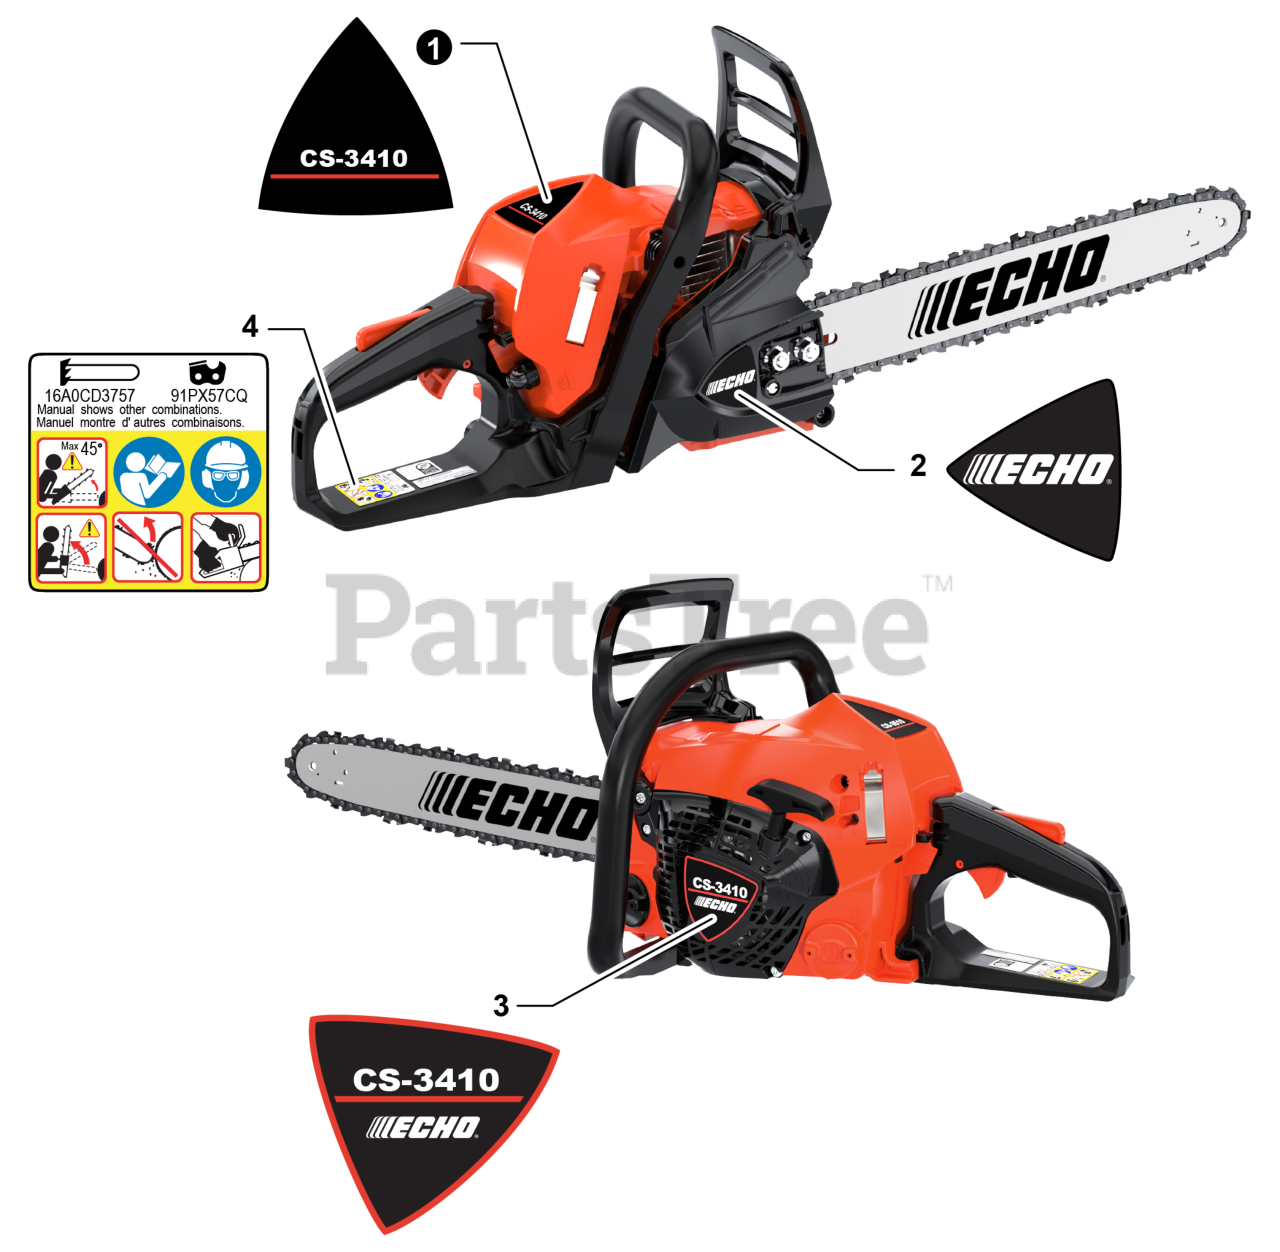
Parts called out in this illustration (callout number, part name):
1	LABEL - MODEL CS-3410
2	LABEL - ECHO
3	LABEL - RECOIL STARTER
4	LABEL - CAUTION
